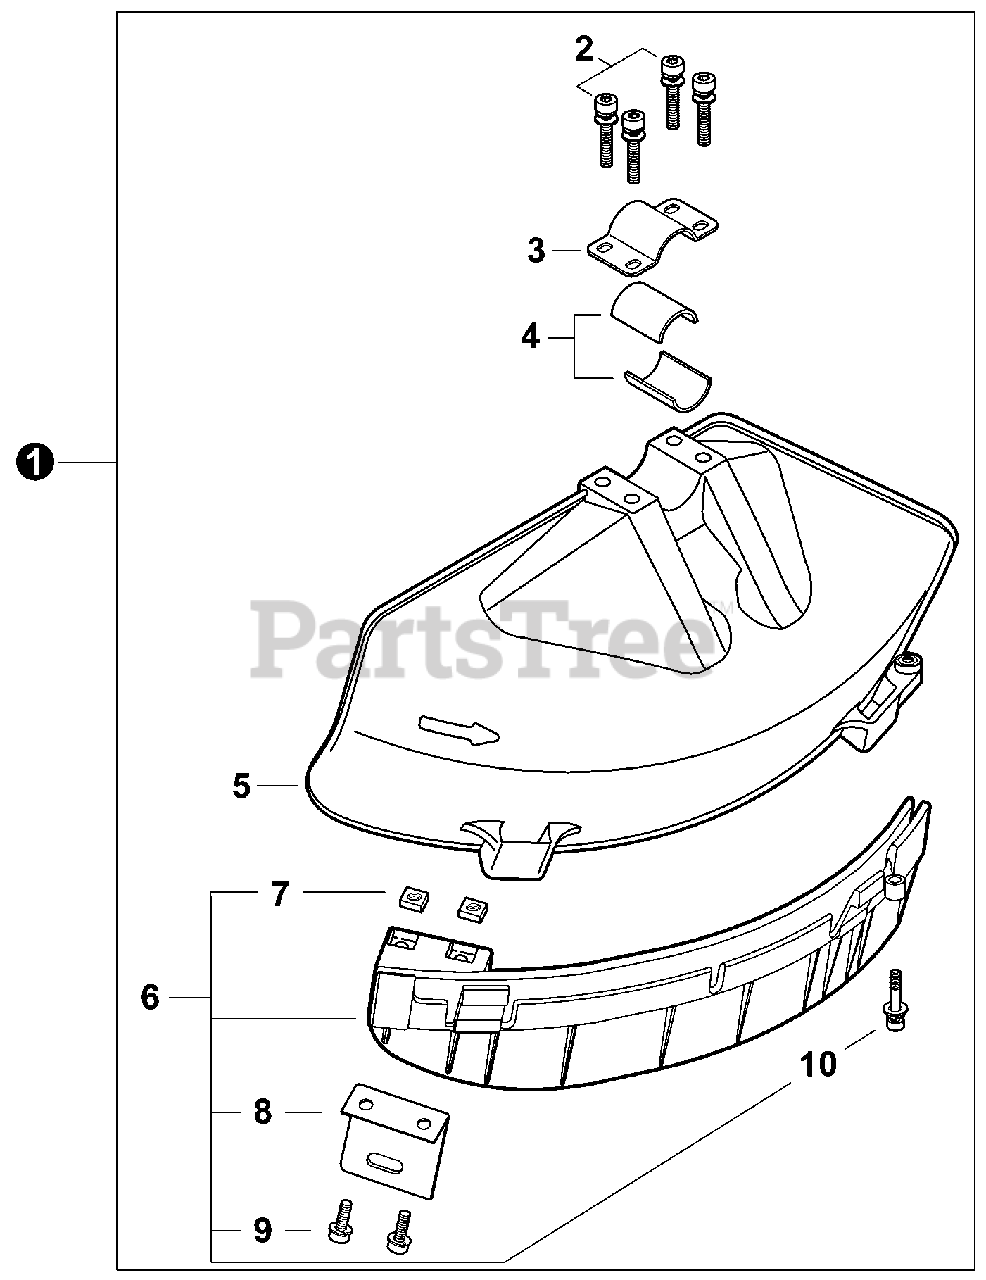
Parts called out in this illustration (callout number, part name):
1	DEBRIS SHIELD KIT
2	BOLT M5x45
3	CLAMP, UPPER
4	SPACER 24
5	SHIELD, DEBRIS - BLADE
6	DEBRIS SHIELD EXTENSION ASSY
9	BOLT 5x16
10	BOLT M5x22
